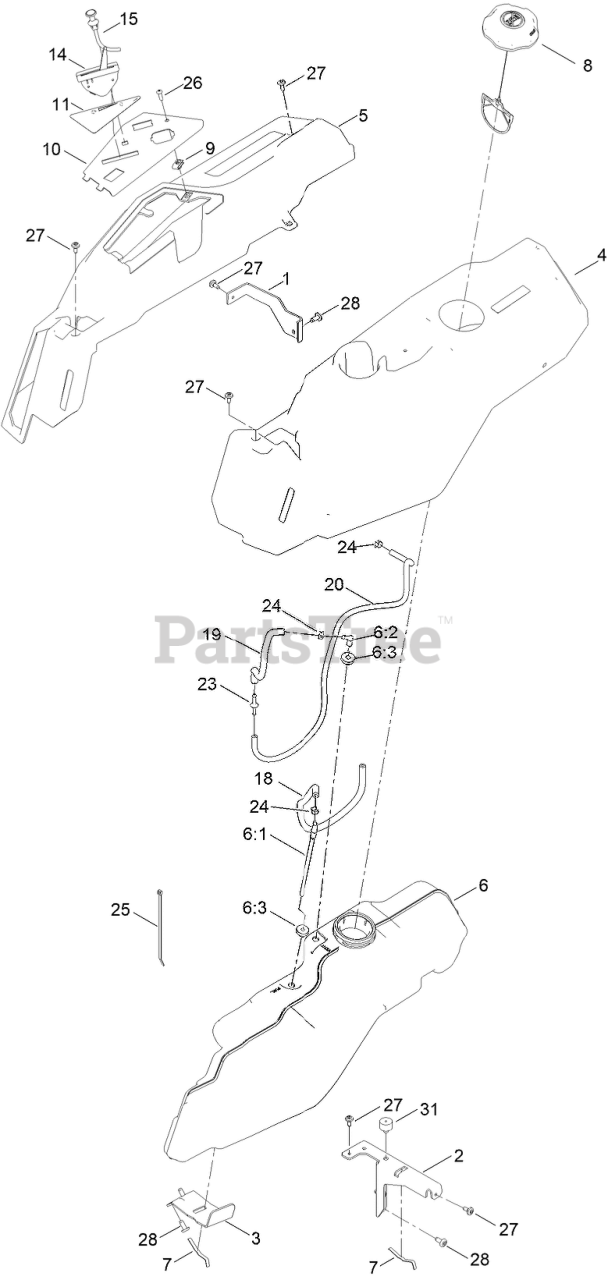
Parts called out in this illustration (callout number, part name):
1	SUPPORT-POD, RH
2	SUPPORT-POD, LH
3	SUPPORT-TANK, FUEL
4	POD-LH
5	POD-RH
6	FUEL TANK ASM
6:1	CONNECTOR-ELBOW, 90 DEG
6:2	FITTING-PLASTIC
6:3	BUSHING
7	SPRING
8	CAP-FUEL, RATCHETING
10	PANEL - CONTROL
11	DECAL-PANEL, CONTROL
14	CABLE-THROTTLE
15	CABLE-CHOKE
18	HOSE-FUEL
19	HOSE-FUEL
20	HOSE-FUEL
23	ADAPTOR-ORIFICE
24	CLAMP-HOSE
25	TIE-CABLE
26	SCREW-PRH
27	SCREW-SHOULDER
31	BUMPER-GROMMET
